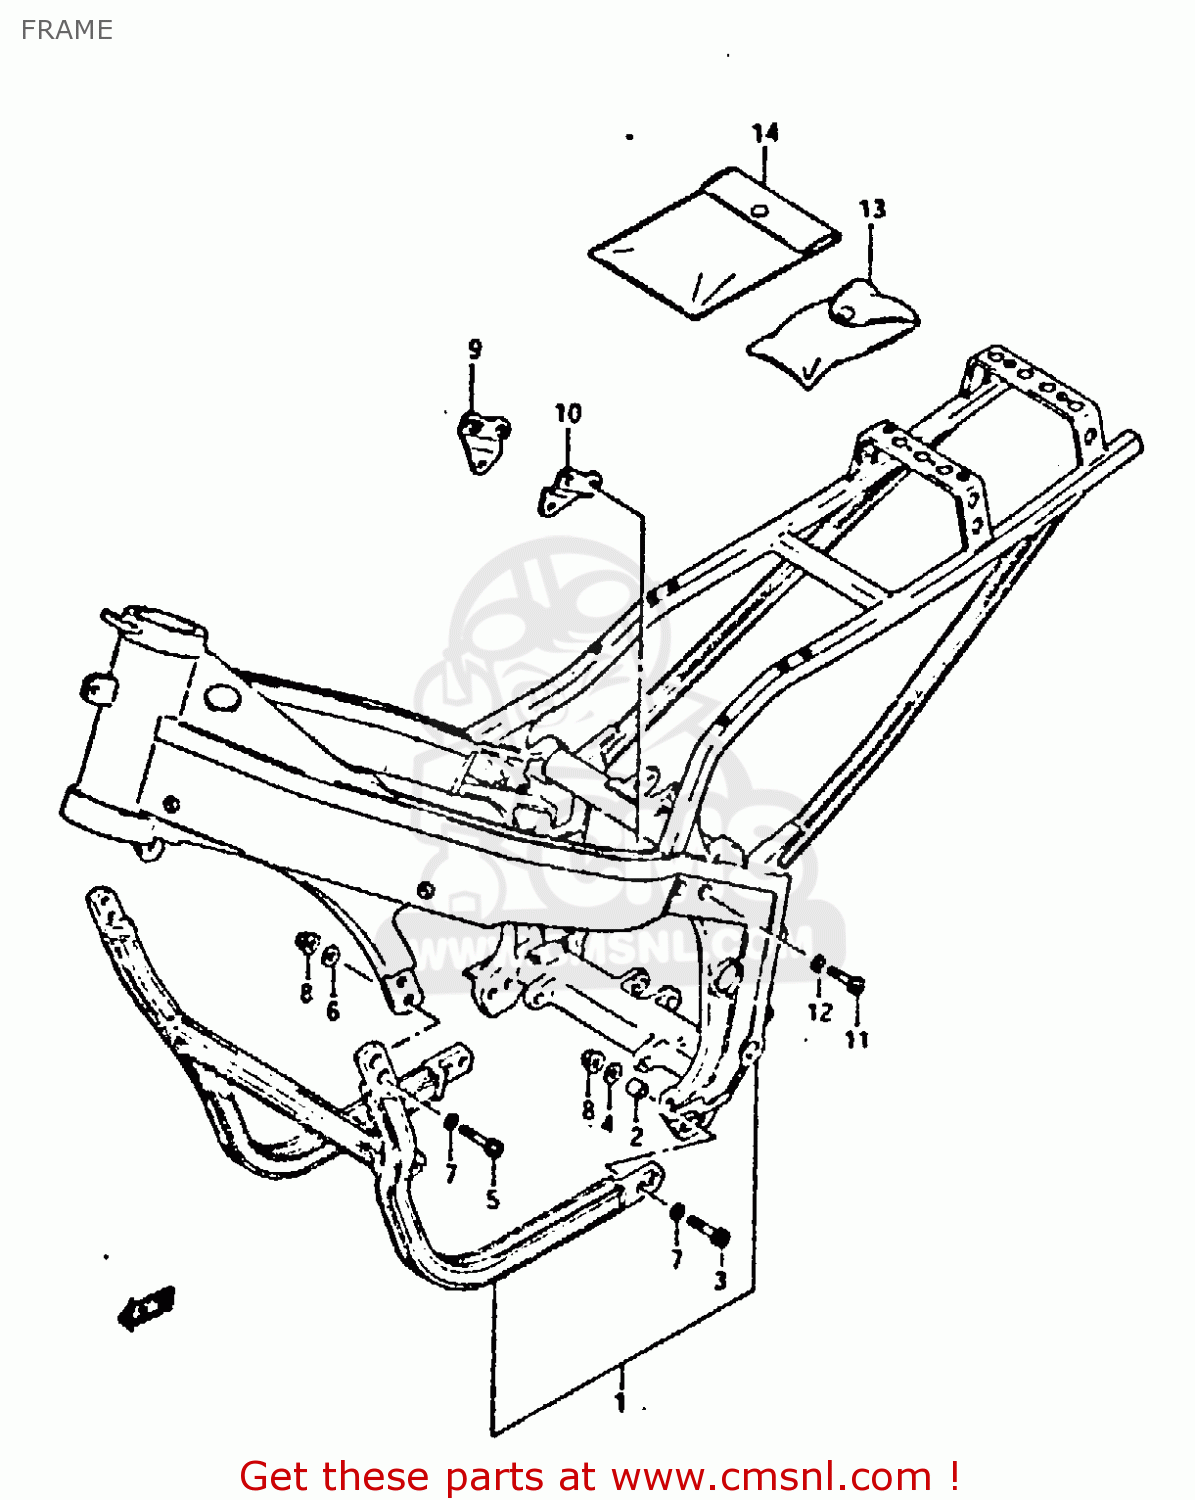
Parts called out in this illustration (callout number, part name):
3	BOLT
5	BOLT, RH
6	WASHER
7	WASHER
8	NUT
11	BOLT, FRONT RH
12	WASHER
13	TOOL ASSY
14	BAG,MANUAL
